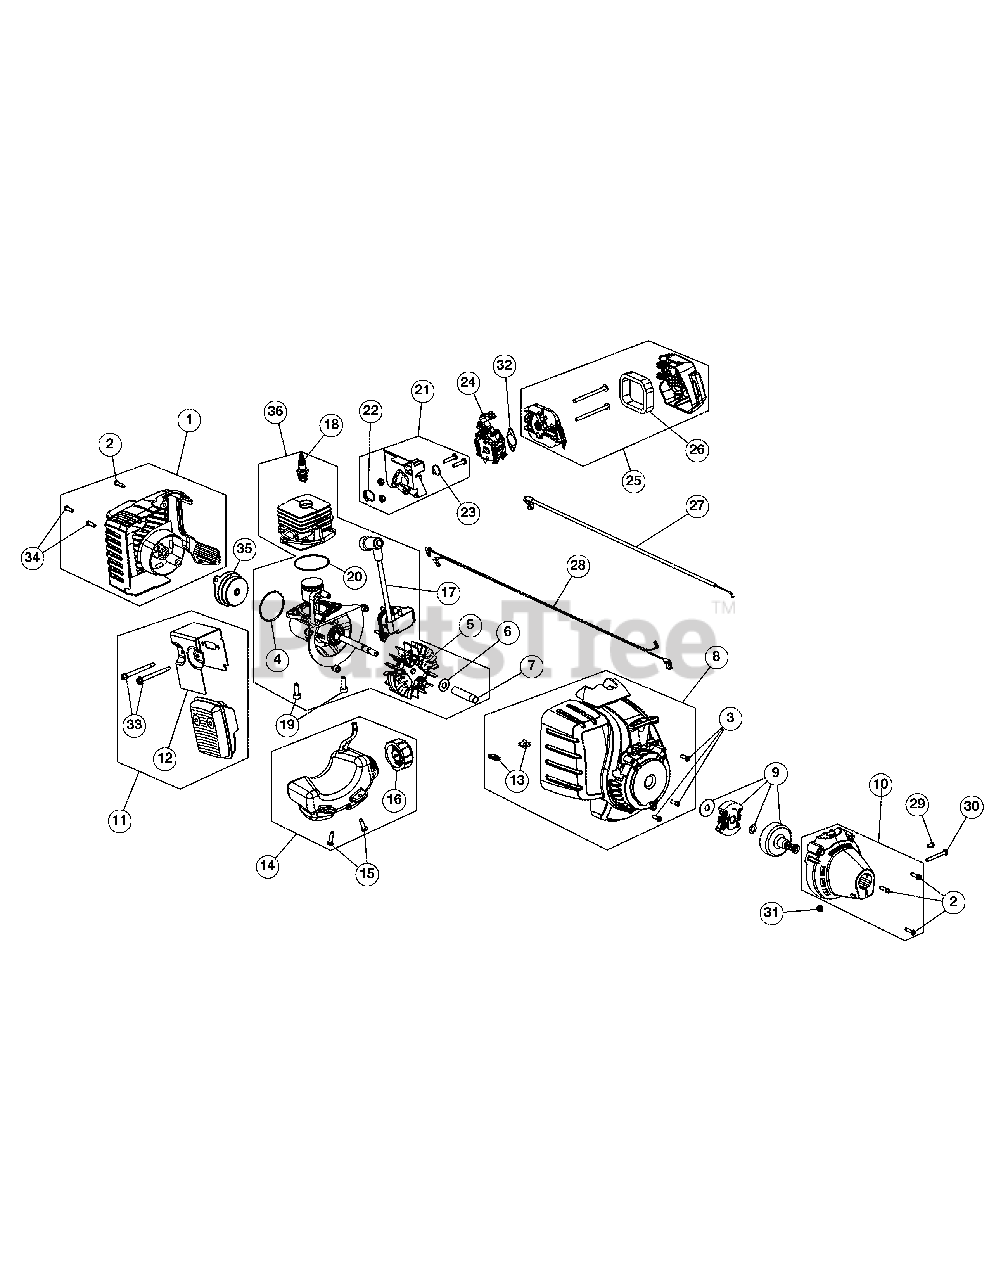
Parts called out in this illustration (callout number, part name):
1	Rear Cover Assembly (Incl. 2 & 34)
2	Cover Screw
3	Housing Screw
4	O-Ring
5	Flywheel Assembly
6	Washer
7	Spacer
8	Starter Housing (Incl. 3 & 13)
9	Clutch Assembly
10	Clutch Cover (Incl. 2)
11	Muffler Assembly (Incl. 12 & 33)
12	Muffler Gasket
13	U-shaped Nut
14	Fuel Tank Assembly (Incl. 15 & 16)
15	Tank Screw
16	Fuel Cap
17	Module Assembly
18	Spark Plug
19	Crankcase Bolt
20	Crankcase O-Ring
21	Insulator Assembly (Incl. 22 & 23)
22	Insulator O-Ring
23	Carburetor O-Ring
24	Carburetor
25	Aircleaner Cover Assembly (Incl. 26)
26	Aircleaner Filter
27	Throttle Cable
28	Lead Wires
29	Anti-rotation Screw
30	Clamp Screw
31	Clamp Nut
32	Air Cleaner Gasket
33	Muffler Screw
34	Rear Housing Screw
35	Electric Starter Cover Assembly
36	Short Block Assembly (Incl. 4-7 & 17-20)
